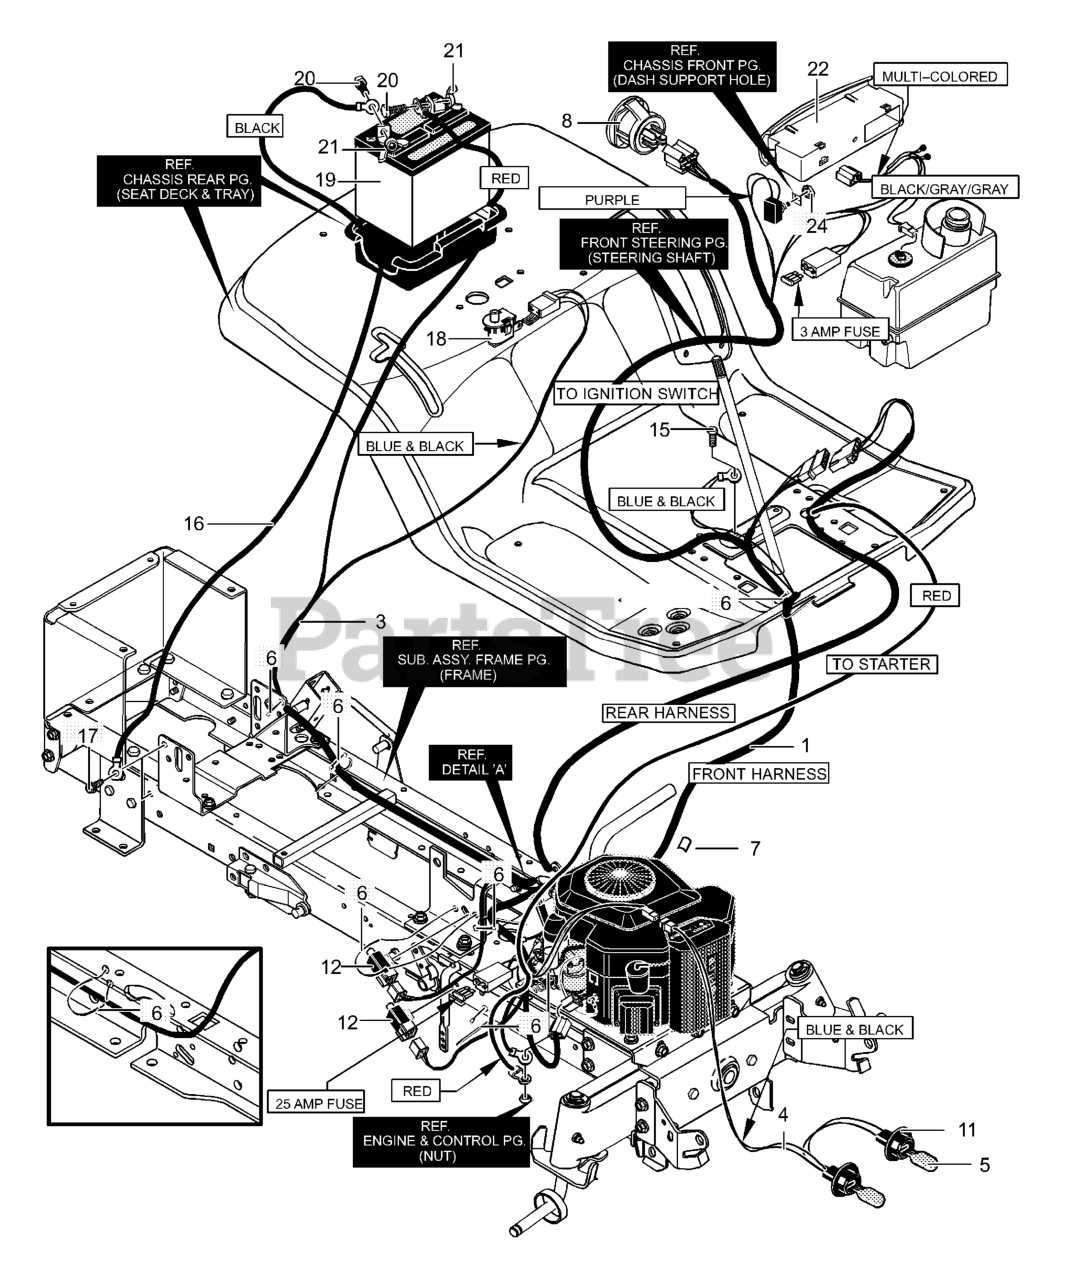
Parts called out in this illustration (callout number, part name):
1	WIRE HARNESS
3	WIRE HARNESS, REAR 20HP
4	WIRE ASSEMBLY, HEADLIGHTS
5	BULB, LIGHT
6	TIE, CABLE
7	WIRE CLIP, ADHESIVE
8	SWITCH, IGNITION
11	SOCKET, LAMP
12	SWITCH, SAFETY
16	WIRE, GROUND
18	SWITCH, SEAT
19	BATTERY
20	BOLT, 1/4-20X.63
21	NUT, WING 1/4-20
22	ELECTRONIC DIAG
24	NUT, PLASTIC
